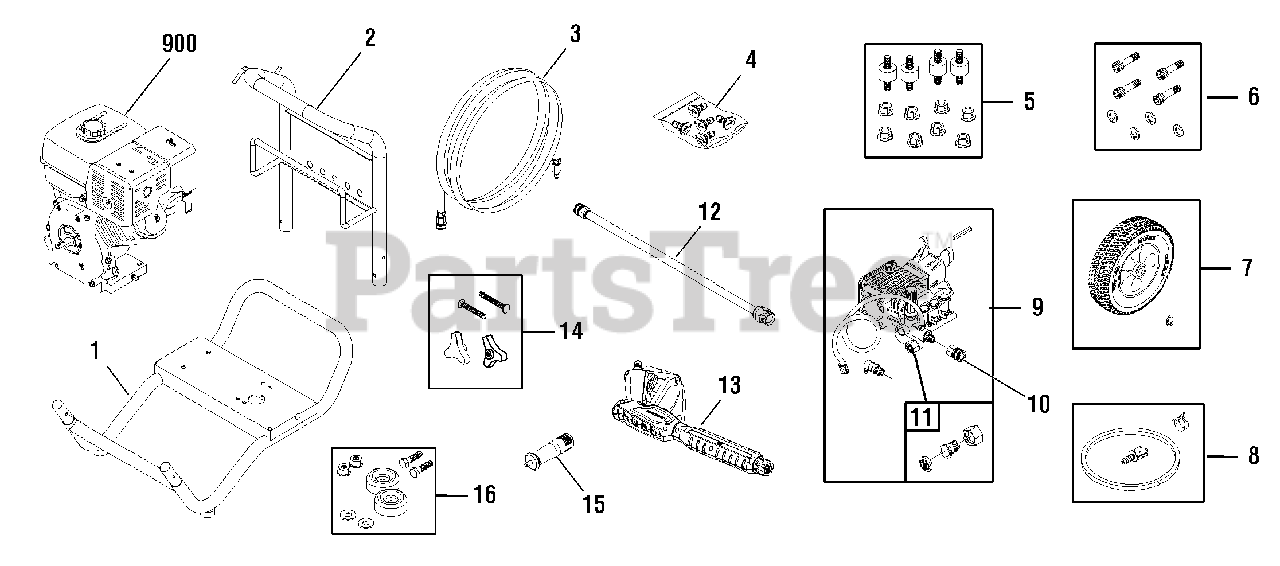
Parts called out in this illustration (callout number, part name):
4	KIT, QC Nozzles
5	KIT, Hardware, Engine Mounting
6	KIT Hardware, Pump Mounting
9	PUMP
10	FITTING
11	ADAPTER, Garden Hose
12	EXTENSION, QC
14	KIT, Hardware, Handle
16	MOUNT, Vibration
900	* ENGINE
